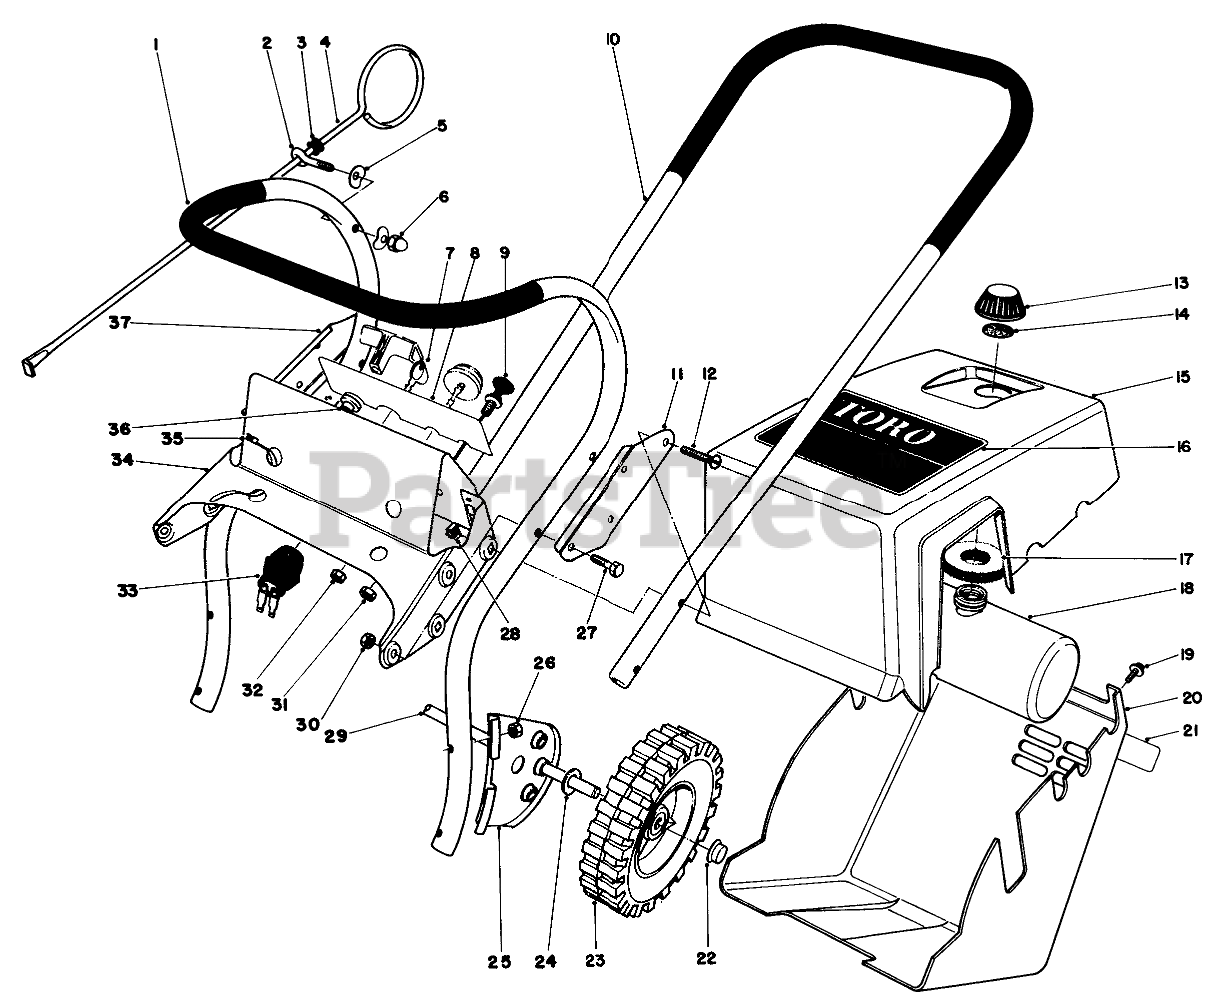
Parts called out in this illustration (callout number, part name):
1	Lower Handle
2	Bolt-Eye
3	GROMMET
4	Vane Adj. Rod
5	WASHER
6	NUT-CAP
7	Key
8	CONTROL PANEL DECAL
9	CHOKE CONTROL
10	Upper Handle
11	SPLICE PLATE
12	Sems Mach. Screw
13	Gas Cap Assy. (Incl. Ref. #14)
14	Gasket
15	Shroud (Incl. Ref. #16)
16	Decal-Toro
17	FOAM PAD
18	Gas Tank Assembly (Incl. Ref. #13)
19	SCREW-HWHTF
20	Lower Shroud (Incl. Ref. #21)
21	Decal-Instruction
22	RETAINER-PUSH ON
23	WHEEL
24	WASHER-FLAT
25	WHEEL BRKT B
26	NUT-HEX
27	SCREW-HH
28	Nut Retainer
31	PAL NUT/CHOKE CNTRL
32	NUT-KEPS
33	SWITCH-ON / OFF
34	Tank Support & Control Panel (Incl. Ref. #8)(Used on units with Serial No. 1000001 thru 1010000)
35	Strap
36	GUIDE-ROPE, STARTER
37	Plate-Splice
